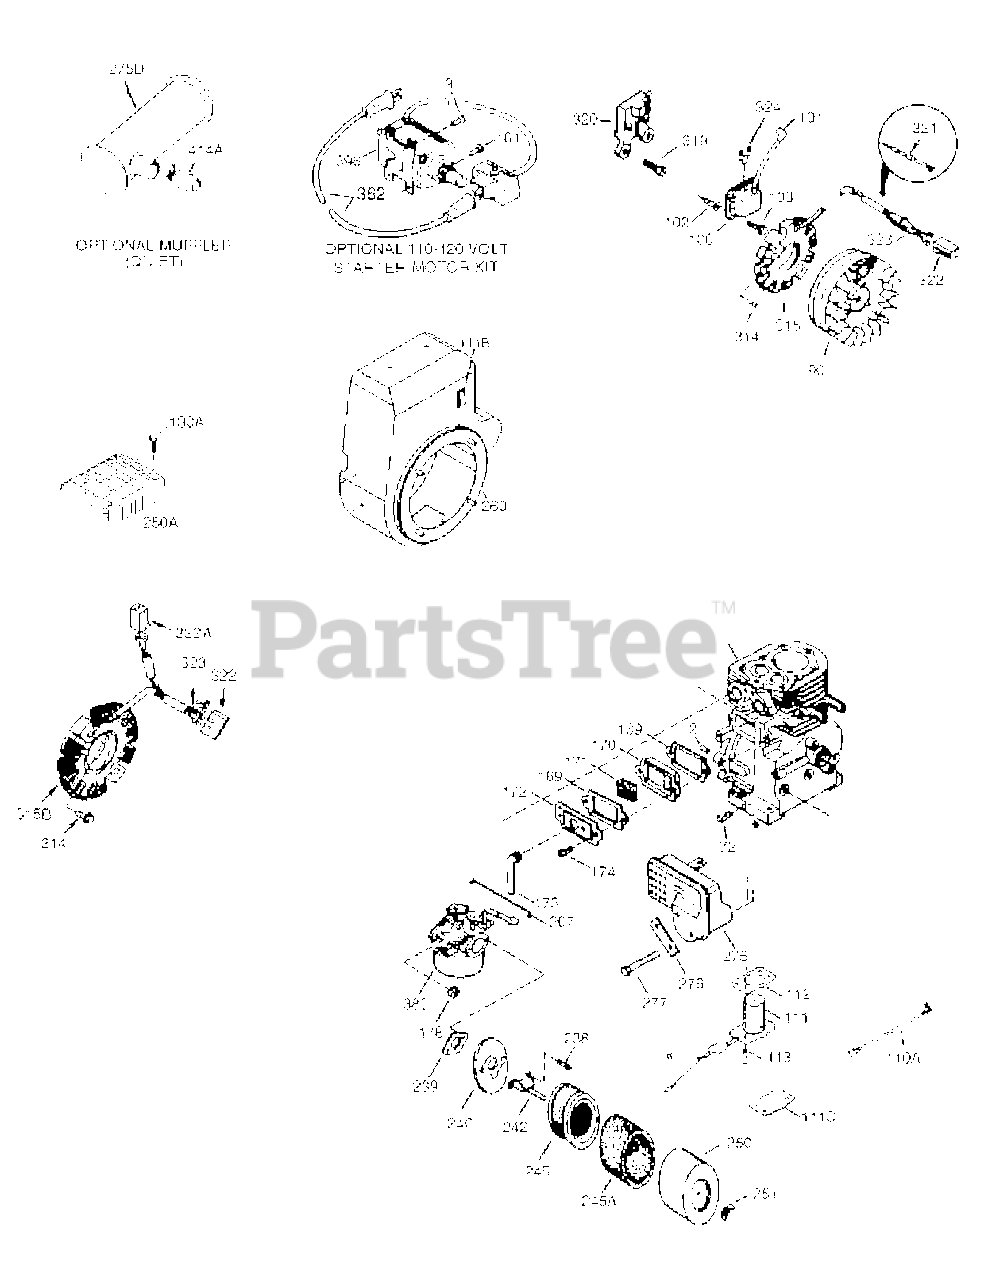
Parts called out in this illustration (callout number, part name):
1	Cylinder (Cast Iron Liner) (3-5/16")
2	Dowel Pin
3	Screw, 1/4-20 x 1/2"
90	Flywheel (w/ring gear)
100	Solid State Ignition (Incl. 101)
101	Spark Plug Cover
102	Solid State Mounting Stud
103	Screw, T-15, 10-24 x 15/16"
130	Screw, 5/16-18 x 1-1/2"
130A	Screw, 5/16-18 x 1-3/4"
130C	Screw, 5/16-18 x 39/64"
169	Valve Cover Gasket
170	Breather Body
171	Breather Element
172	Valve Cover
173	Breather Tube
174	Screw, 10-24 x 1/2"
178	Nut & Lock Washer 1/4-28
182	Screw, 1/4-28 x 1"
207	Throttle Link
222	Screw, 10-32 x 1/2"
260	Blower Housing
264A	Screw, 1/4-20 x 5/8"
276	Locking Plate
277	Screw, 5/16-18 x 4-3/16"
298	Screw, 1/4-15 x 3/4"
311	Oil Fill Plug Incl. 312)
314	Screw, 1/4-20 x 3/4"
315	Alternator Coil (3/5 Split)
322	Connector Body
361	Screw, Torx T-30, 1/4-20 x 15/32"
361A	Screw, 6-32 x 2-1/2"
380	Carburetor (Incl.184)
396	Electric Starter Motor (120 Volt)
396	Electric Starter Motor 120 Volt
999	Winter Maintenance Kit
